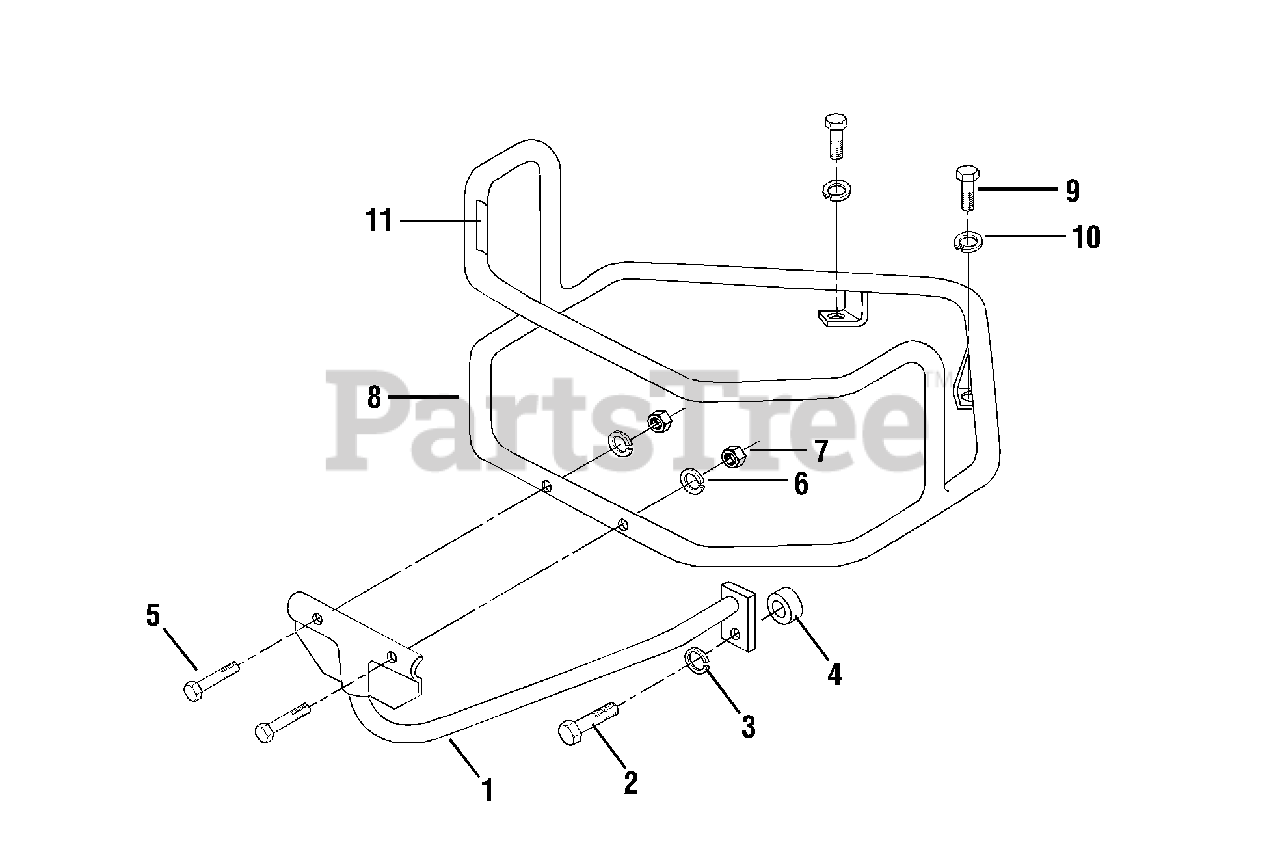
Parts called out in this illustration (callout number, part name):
1	Brace - bumper bottom
2	Bolt - hex hd., 1/2-13 x 1-1/2"
3	Lockwasher - spring lock, 1/2"
4	Spacer, 1/2"
5	Bolt - hex hd., 5/16-18 x 1-1/2"
6	Lockwasher - spring lock, 5/16"
7	Nut - hex, 5/16"-18
8	Bumper wraparound
9	Bolt - hex hd., 3/8-16 x 1"
10	Lockwasher - spring lock, 3/8"
11	Decal
